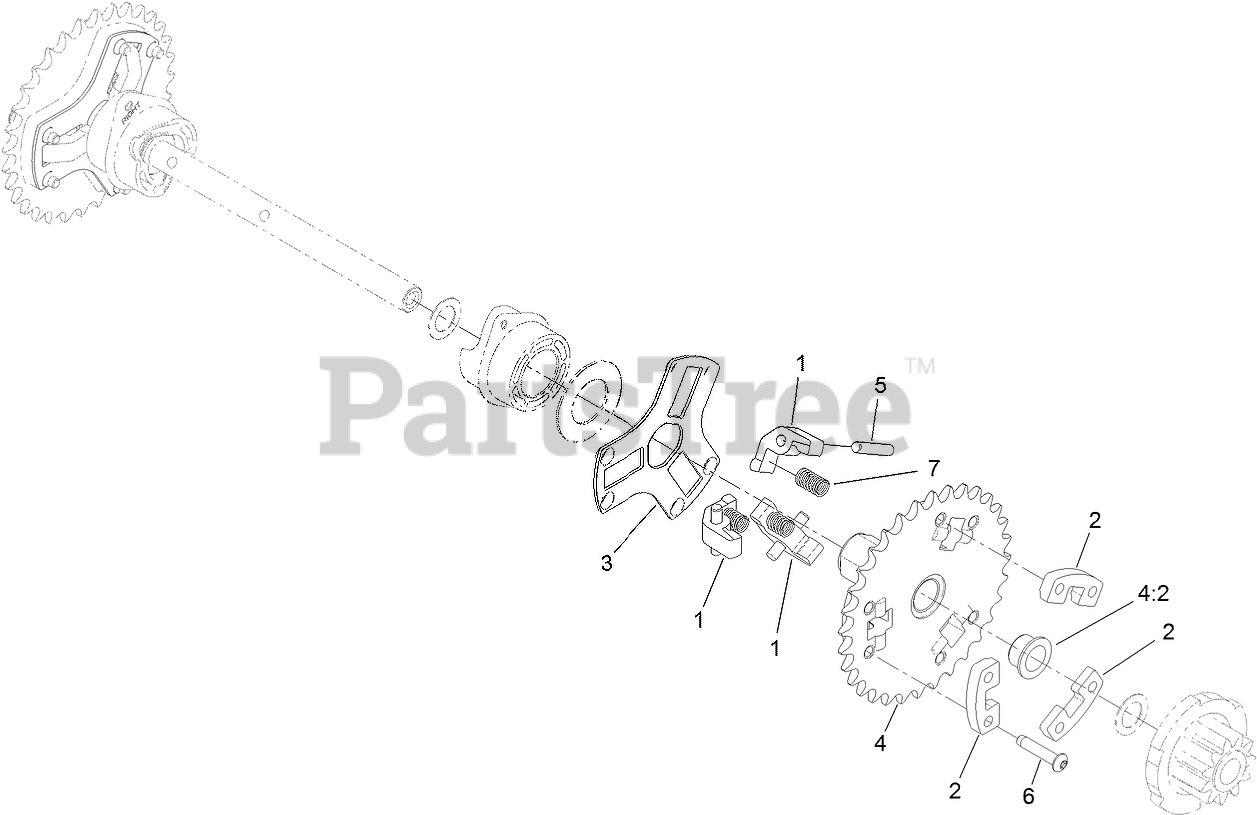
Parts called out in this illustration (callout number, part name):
1	PAWL-CLUTCH
2	SUPPORT-PAWL
3	RETAINER-PAWL PIN
4	32T SPROCKET ASM
4:2	BUSHING-FLANGE
5	PIN-DOWEL
6	SCREW-BHCS
7	SPRING-COMPRESSION
